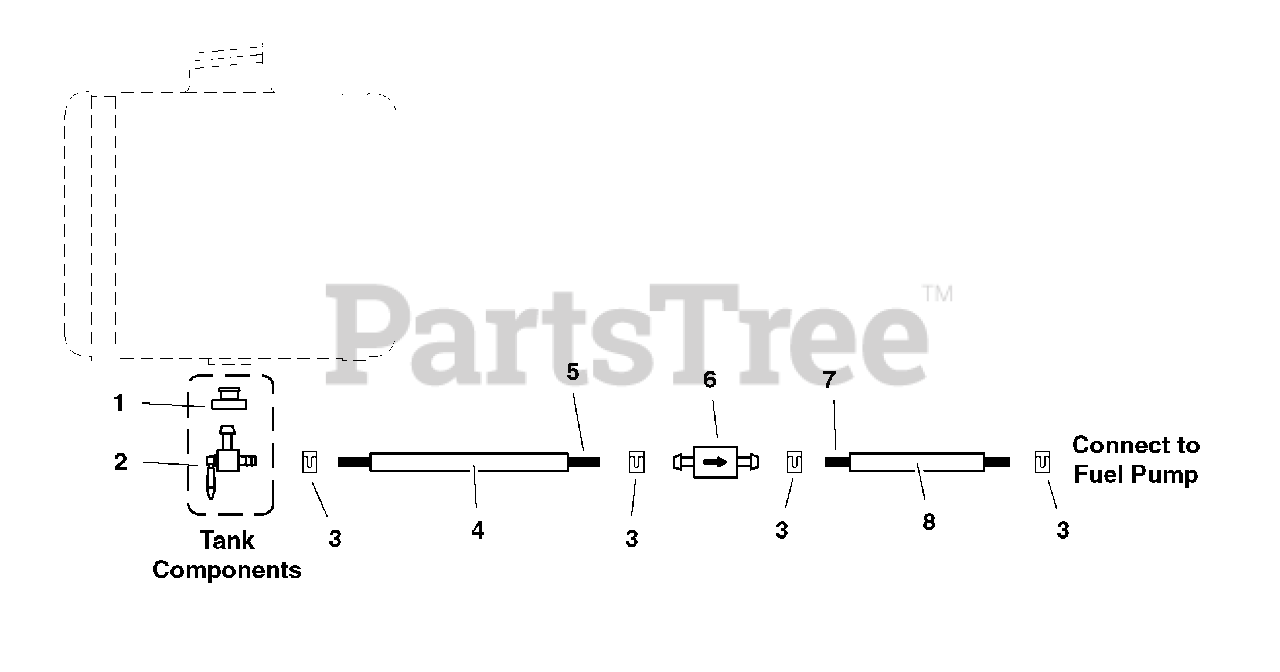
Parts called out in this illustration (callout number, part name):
1	BUSHING-FUEL TANK RED RUBBER (SV)
2	FUEL SHUTOFF VALVE
3	CLAMP, Hose
4	WIRE LOOM, 24"
7	HOSE, 19"
8	WIRE LOOM, 16"
